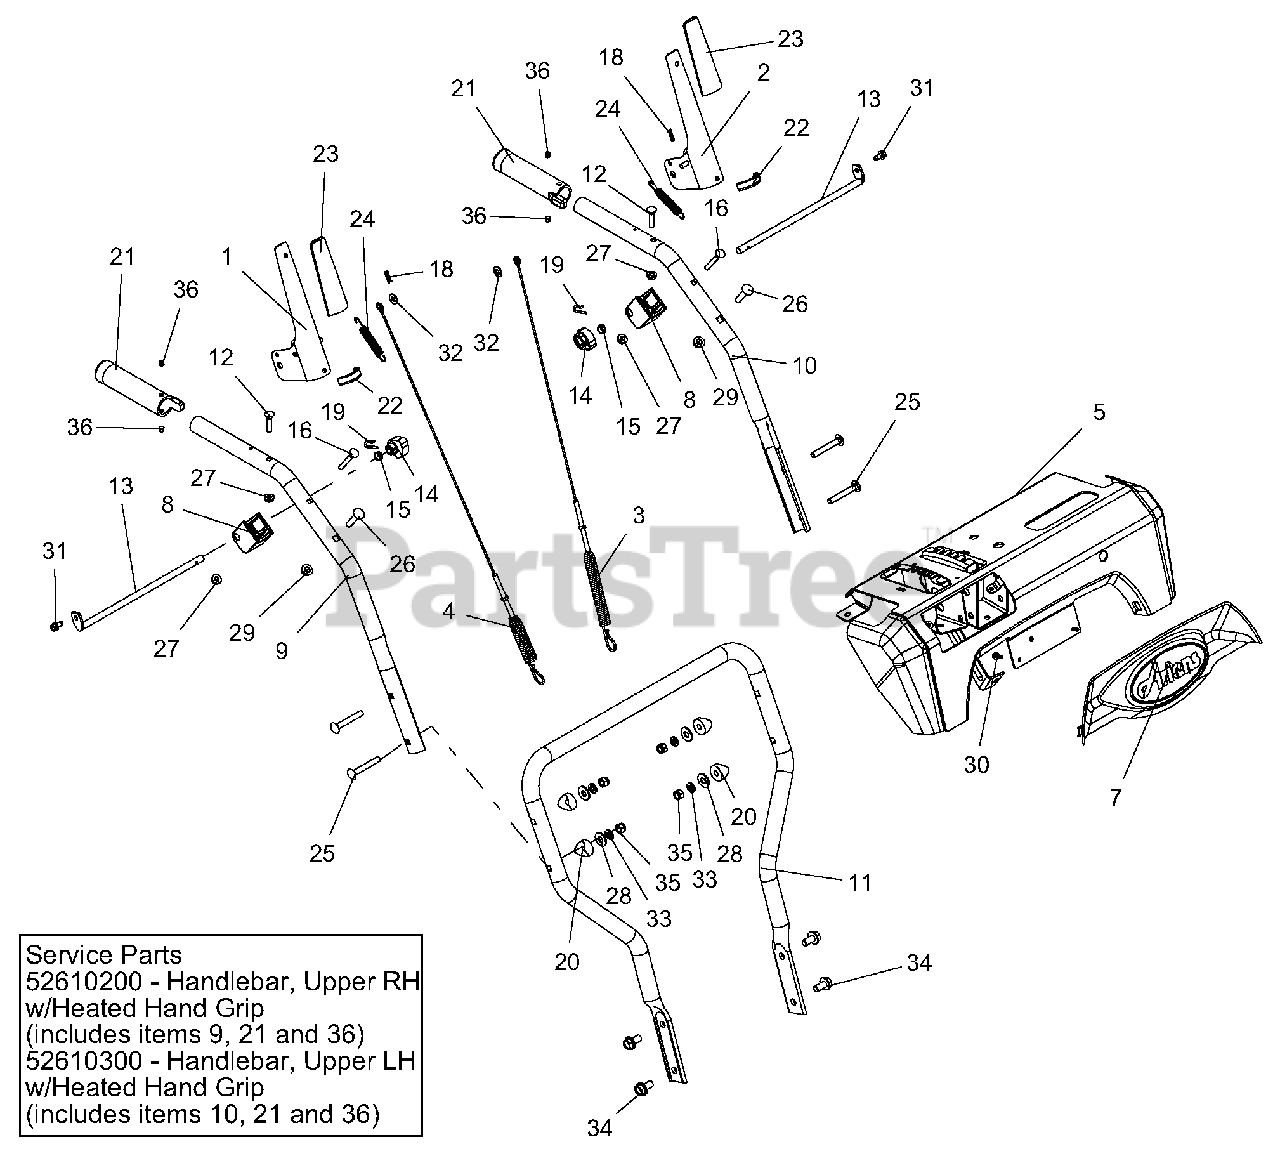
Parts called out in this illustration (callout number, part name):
1	LEVER, CLUTCH-RH
2	LEVER, CLUTCH-LH
3	CABLE, UPPER TRACTION
4	CABLE, AUGER (DELUXE & PRO)
5	CONTROL PANEL W/DECAL QT,AD,HW
7	DASH BEZEL, ARIENS LOGO - PRO
8	BLOCK, CLUTCH PADDLE
9	HANDLEBAR, UPPER - RH
10	HANDLEBAR, UPPER - LH
11	HANDLEBAR, LOWER - DELUXE
12	BLT-RDHDXLSQNK.25-20X1.25 G5ZC
13	ROD, PADDLE MOUNT - PRO
14	CAM, INTERLOCK
15	BUSHING, POLYLINER-.38 SNAPIN
16	BLT-RDHDXLSQNK .25-20X2.0 G5YZ
18	PIN-HAIR INT .06X.18X.77
19	PIN, SPRING CLIP
20	SPACER, HANDLEBAR
21	HEATED GRIP, MAGURA
22	EDGING, CLUTCH PADDLE - 2.00"
23	CLUTCH PADDLE SLEEVE - GRAY
24	SPRING, EXTENSION
25	@BLT-RDHDSQNK .31-18X2.25 G5YZ
26	@BLT-RDHDSQNK .31-18X1.50 G5YZ
27	@NUT-LK-CTR-FLG .25-20 YWZC
28	@WSHR-FL-STL.38X.875X.083 YWZC
29	@NUT-LK-TOP-FLG .31-18 YWZC
30	SCR-TAP #10X.50 BOSS INDHXHD
31	SCR-TAP .25-20X.50 HWH TR YWZ
32	@WSHR-FL-STL.281X.62X.065 YWZC
33	WSHR-LK .312X.097 HVY YWZC
34	BLT-SERHFWH .38-16X.75 YWZC
35	@NUT-LK-NYL .312-18 YWZC
36	RVT-POP #43 .125X.313 STL ZINC
